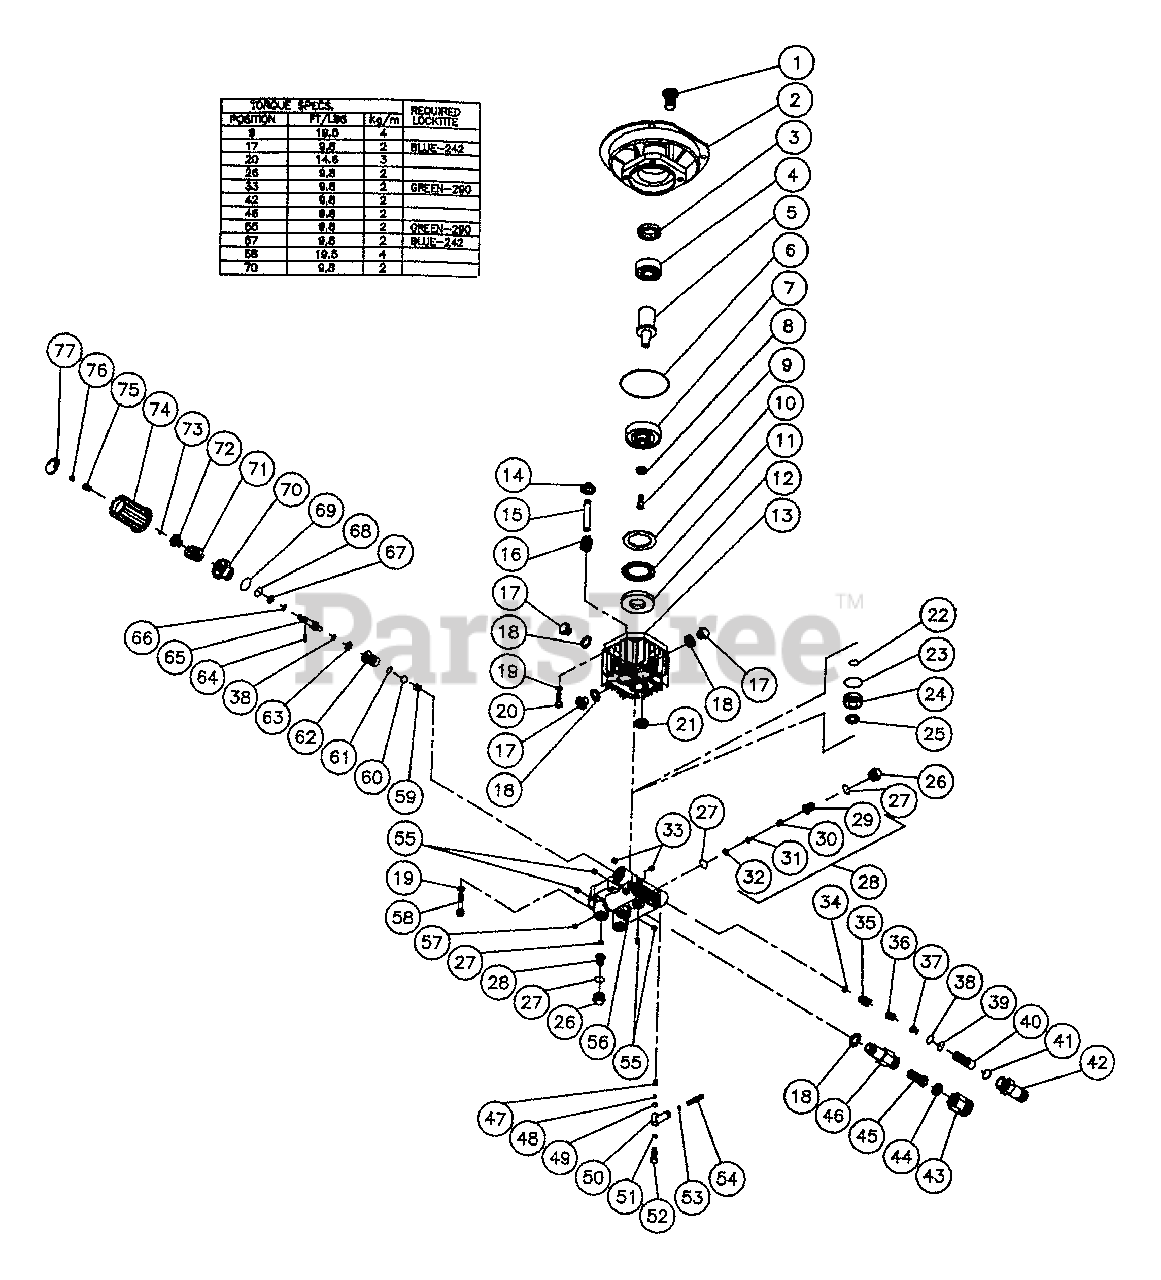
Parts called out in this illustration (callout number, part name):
3	Oil Seal
7	Wobble Plate
10	Bearing Disc
12	Bearing Disc
13	Pump Housing
14	Piston Spring Retainer
16	Piston Spring
17	Oil Drain Plug
19	Lockwasher
21	Oil Seal (See 07575-06)
22	O-ring (See 07575-04)
23	O-ring (See 07575-04)
24	Packing Retainer
25	Pressure Seal (See 07575-04)
26	Valve Plug
28	Valve Complete (See 07628-64)
29	Valve Cage (See 07628-64)
30	Valve Spring (See 07628-64)
31	Valve Plate (See 07628-64)
32	Valve Seat (See 07628-64)
35	No Return Valve
37	Injector Nozzle
40	Injector Bushing
42	Outlet Connector
43	Garden Hose Connection
45	Filter Inlet
46	Inlet Connector
47	Spring (See 07628-67)
48	Ball (See 07628-67)
49	O-ring (See 07628-67)
50	Plastic Fitting
51	O-ring (See 07628-67)
52	Banjo Fitting
54	Hose Barb
56	Pump Manifold
62	Valve Seat
63	Back-up Ring
64	Roll Pin
65	Piston By-pass Valve (See 07575-45)
67	Back-up Ring
70	Body By-pass Valve
71	Pressure Regulator Spring-1500 PSI
72	Pressure Regulator Screw
73	Snap Ring
74	Pressure Regulation Knob
